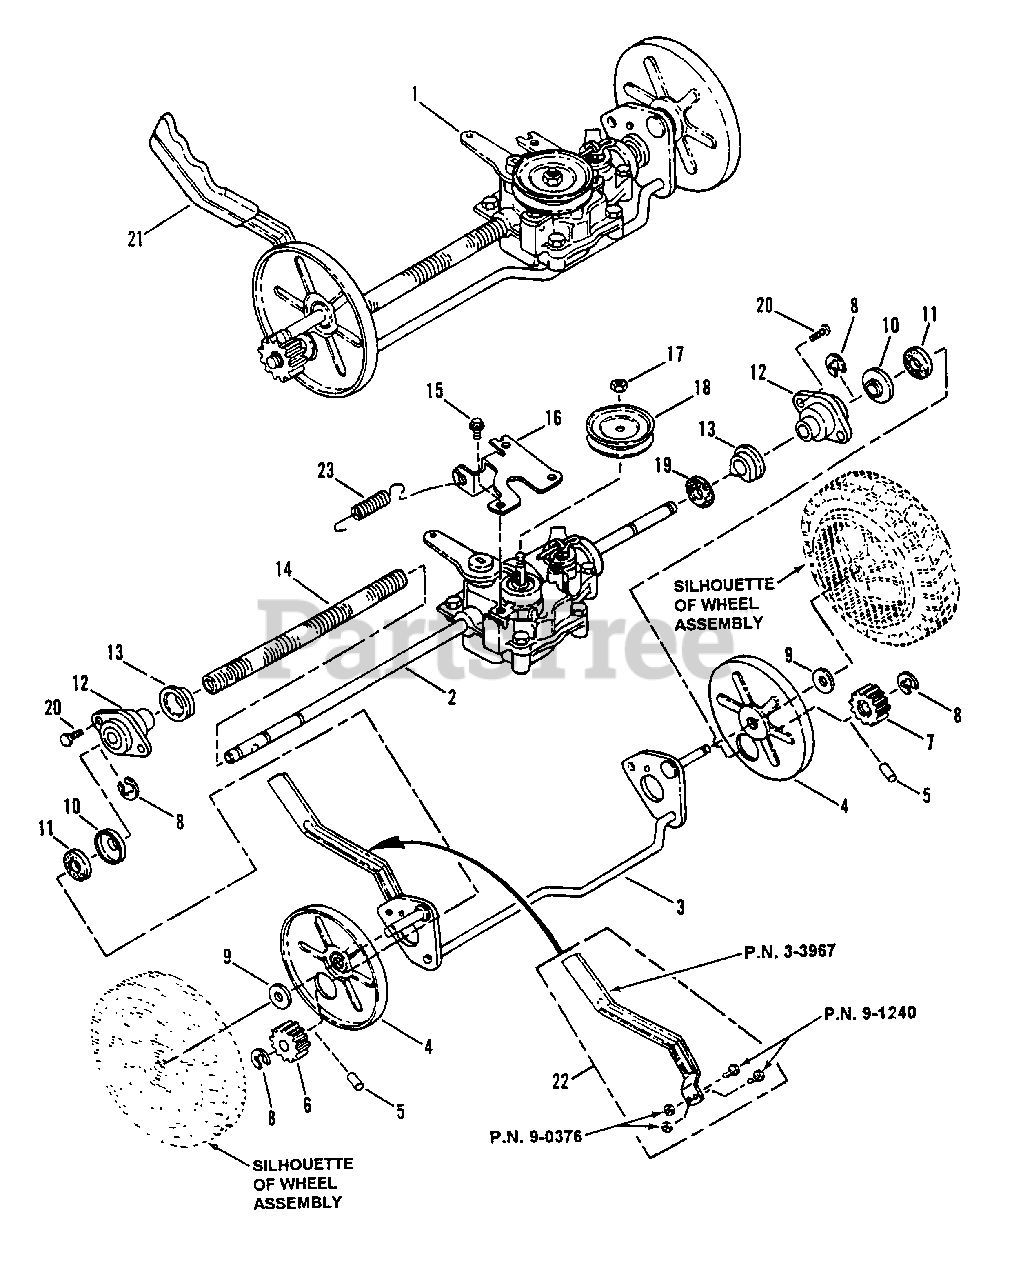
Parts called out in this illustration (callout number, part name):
1	AXLE/TRANSMISSION ASSEMBLY
2	ASSEMBLY, Transmission
3	ASSEMBLY, Rear Axle Weldment
4	SHIELD, Dust
5	PIN, Pawl, 3/16 O.D.
6	PINION, Right Hand Drive
7	PINION, Left Hand Drive
8	RING, Retaining
9	WASHER, .531 I.D. x 1.50 O.D.
10	RETAINER, Pinion Seal
11	SEAL, Pinion (Felt)
12	ASSEMBLY, Bearing Carrier
13	BUSHING, Rear Axle
14	TUBING, 5/8" I.D., Convoluted
15	SCREW, 5/16-18 x 5/8" Hex Washer Head, Self-Tapping
16	BRACKET, Transmission
17	NUT, M10-1.50 Hex Nyloc
18	PULLEY, Transmission
19	WASHER, Felt
20	SCREW, 1/4-20 x 3/8" Hex Washer Head, Self-Tapping
21	GRIP, Height Adjust Lever
22	KIT, Height Adjusting Lever
23	SPRING, Transmission Extension (Short)
33967	LEVER, Height Adjusting
90376	NUT, #10-32 Hex Nyloc
91240	SCREW, #10-32 x 5/8" Hex Washer Head, Grade 5
